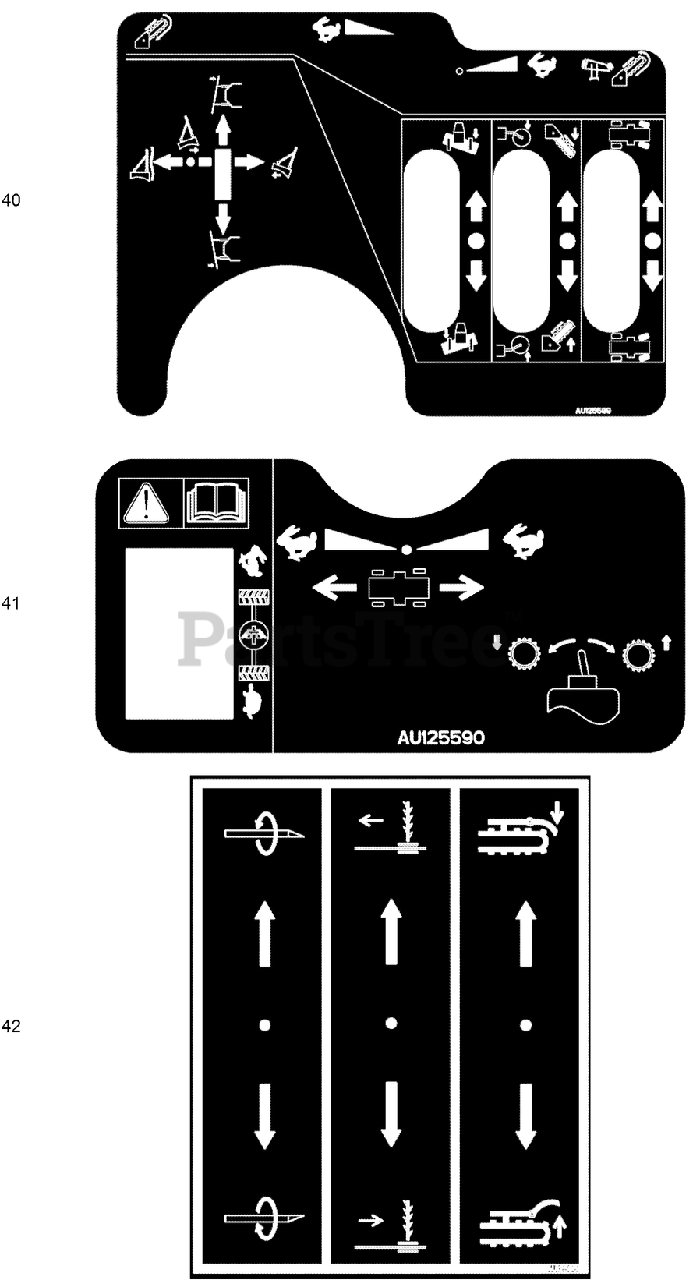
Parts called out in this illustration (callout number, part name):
40	DECAL-Controls, RH
41	DECAL-Controls, LH
42	DECAL-Auxiliary Valve
